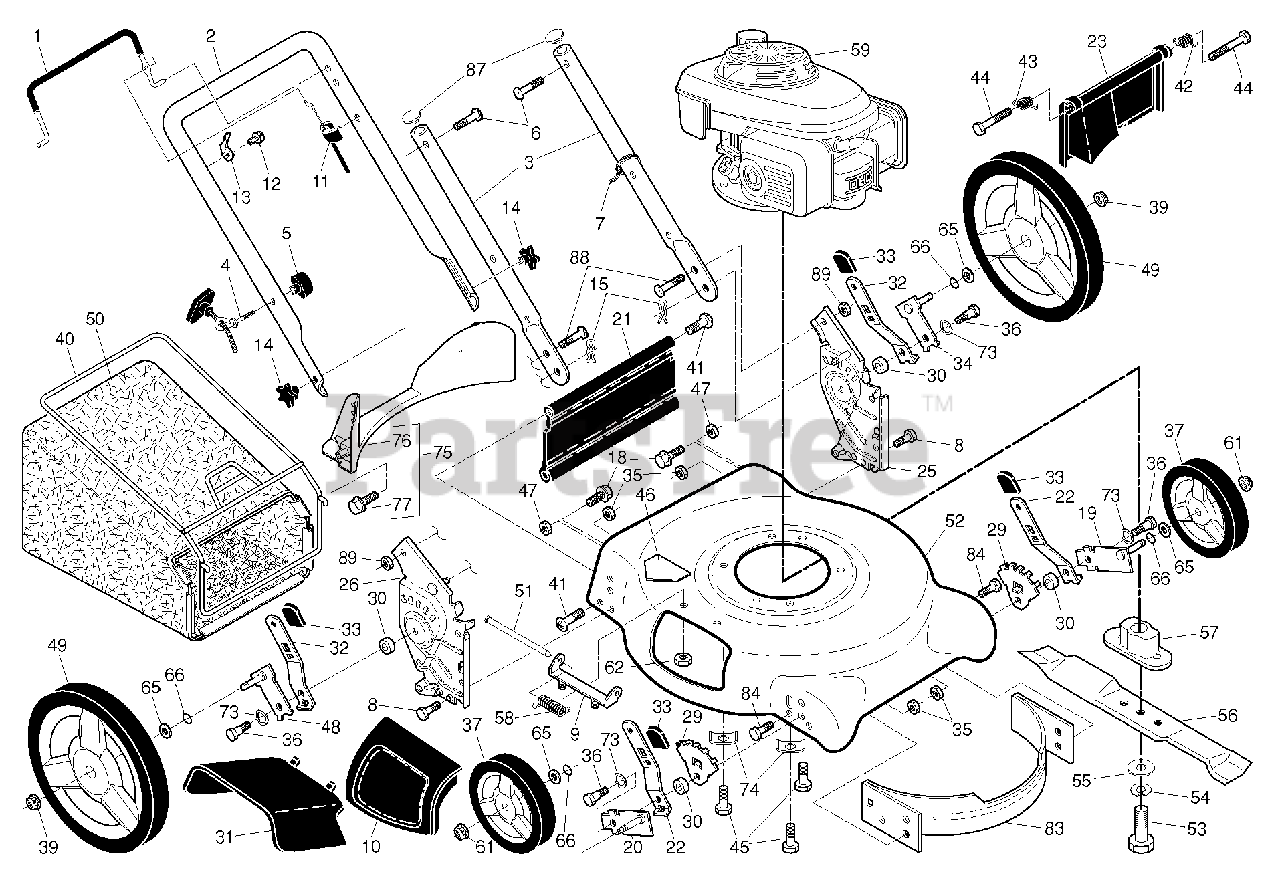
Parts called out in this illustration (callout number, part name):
1	BAIL.OVER.MOLD.ERGO.MZR.ORANGE
2	HANDLE.UP.CURV.PUSH/SSDRV.GREY
3	HANDLE.LOWER.DOME.BT.GREY
4	GUIDE.ROPE.BLK.ZINC.CHROM
5	T-KNOB.NEW ROPE GUIDE
6	BOLT, HANDLE 5/16-18X1.75
7	TIE GUIDE
8	BOLT
9	BRACKET.ASM.HOUSING.EZ.MUL
10	DOOR.MULCH.21".REAR.PUSH.GRAY
11	CABLE.ASM.ZONE.CONTROL
13	BRACKET.UPSTOP.RT
14	KNOB.HANDLE.PLASTIC.STAR.BLACK
15	HAIRPIN COTTER
18	SCREW 1/4X20
19	AXLE ARM ASSY FRONT LH
20	AXLE ARM ASSY FRONT RH
21	RP_KIT.SKIRT.21 DOMED.W/LIP
22	SELECTOR SPRING, FRONT
23	DOOR.REAR.21.DOMED.498
25	BRACKET.ASM.HAND.HW.21.LT.GREY
26	BRACKET.ASM.HAND.HW.21.RT.498
29	WHEEL ADJ BRACKET FRONT
30	SPACER.HEIGHT.ADJUSTER(2 2)3 2
31	DEFLECTOR.CLIPPING.21.GREY
32	SPRING.SEL.22.ECON.HI-WHL.RATO
33	SELECTOR KNOB
34	AXLE ARM ASSY REAR LH
35	NUT.LOCK.5/16-18
36	SHOULDER BOLT 5/16-18
37	WHEEL & TIRES ASSY, FRONT
39	NUT.HEX.FLANGE.3/8-16.LOCKNUT
40	FRAME.BAG.21.REAR.DOMED.PUSH
41	SCREW.1/4-20X21/4.HEX.
42	SPRING.LH.22.REAR.DOOR.EZ.EMPT
43	SPRING.RH.22.REAR.DOOR.EZ.
45	BOLT 3/8-16X1-1/8
46	DANGER DECAL
47	NUT.FLANGE.HEX.5/16X18.BLACK
48	AXLE ARM ASSY REAR RH
49	WHEEL.12 X 1.75 CFH3SPK.RAD3
50	GBAG.2323029ER.HU.VENT.GRY.SIL
51	ROD.HINGE.COMBI-C
52	HOUSING.21.M/C.DOME.ORANGE
53	SCREW, HEX HD 3/8-24 X 1-3/8
54	LOCKWASHER
55	WASHER,HARDEN
56	BLADE.21.4-N-1.PX-3.5STAR.RUST
57	ADAPTER.BLADE.W/KEY.25MM.CE
58	TORSION SPRING
61	NUT.HEX.FLANGE.3/8-16.LO(3 2)
62	LOCKNUT.NYLOC.1/4-20
66	O-RING..070X.487.NEOPRENE
73	WASHER.CURVED.CYLINDRICAL
74	WASHER.ENGINE.BZP
75	KIT.BAFFLE.REAR.PLASTIC.21.RD
76	BAFFLE.REAR.PLASTIC.21.RD.ECON
77	SCREW.HX.13X.750
83	BAFFLE.FRONT.21.DOME.US
84	BOLT.5/16HEX.WHS.HD
87	PLUG.PLASTIC.7/8".14-20.GAUGE
88	BOLT
89	LOCKNUT-FLANGE 5/16-18
